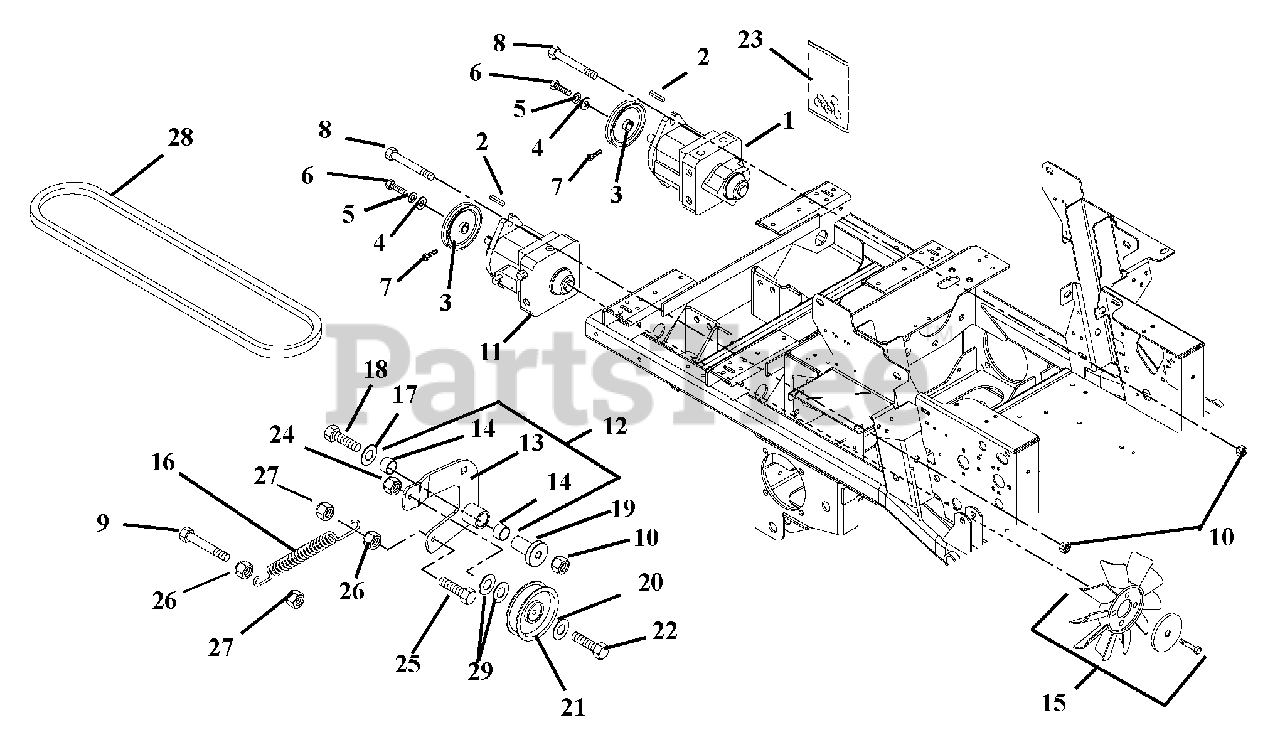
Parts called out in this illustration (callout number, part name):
1	Pump, Hydraulic (RTN) with Auxiliary
1	Pump, Hydraulic (LH) without Auxiliary
2	Key, Square 5 x 5 x 30mm Plain
3	Sheave, Poly-V .671 x 4.125
4	Washer, Pump .28 x 1.25 x .50
5	Washer, Locking .25 x .062
6	Bolt, Hex M6 x 1 x 16
7	Screw, Socket Head .25-20 x .50
8	Bolt, Hex .50-13 x 1.50 Grade 5
9	Bolt, Hex .31-18 x 2.50 Grade 5
10	Nut, Locking Top Flange .50-13
11	Pump, Hydraulic (RTN)
12	Assembly, Idler Arm Guard Drive
13	Weldment, Idler Arm Ground Drive
14	Bearing, 1.00 x 1.12 x .75
15	Fan, Hydro Pump Cooling
16	Spring, Tension .120 x .845 x 6.500
17	Washer, Flat Steel .39 x.75 x.125
18	Bolt, Hex .50-13 x 3.50 Grade 5
19	Bearing, Pedestal Powdered Metal
20	Washer, Flat Steel .406 x .812 x .065
21	Idler, Flat .377 x 4.0 x .96 Poly
22	Bolt, Hex .38-16 x 2.0 Grade 5
23	Kit, Pump Seal
24	Nut, Locking Top Flange .38-16
25	Bolt, Hex .31-18 x 1.25 Grade 5
26	Nut, Hex .31-18
27	Nut, Locking Top Flange .31-18
28	Belt, Poly-V 49.50
29	Washer, Flat Steel .390 x .75 x .125
